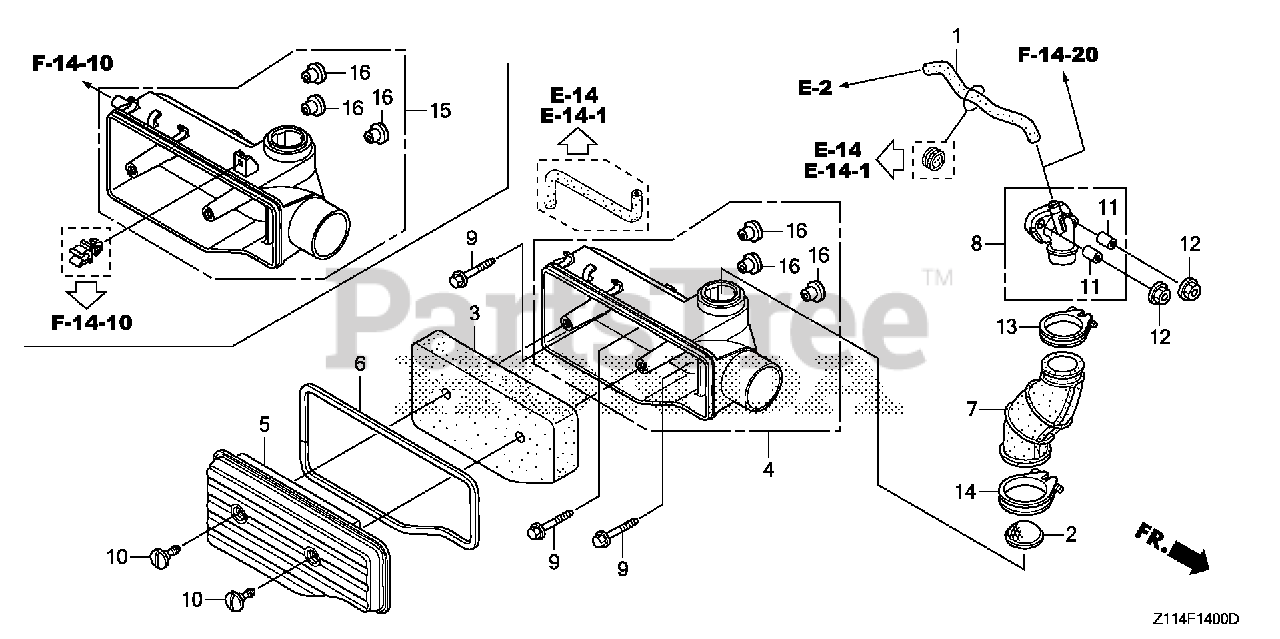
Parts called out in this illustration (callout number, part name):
1	TUBE, BREATHER
2	TRAP, FLAME
3	ELEMENT, AIR CLEANER
4	HOUSING, AIR CLEANER
5	COVER, AIR CLEANER
6	SEAL, AIR CLEANER COVER
7	TUBE, AIR CLEANER CONNECTING
8	JOINT, AIR IN.
9	BOLT, FLANGE (6X23)
10	BOLT, AIR CLEANER COVER (- SCREW)
11	COLLAR, IN. JOINT
12	NUT, FLANGE (6MM)
13	BAND, AIR CLEANER CONNECTING TUBE (46)
14	BAND, AIR CLEANER CONNECTING TUBE (54)
16	COLLAR, FAN COVER (Honda Code 5580527). (N/A: SEE ASSEMBLY)
